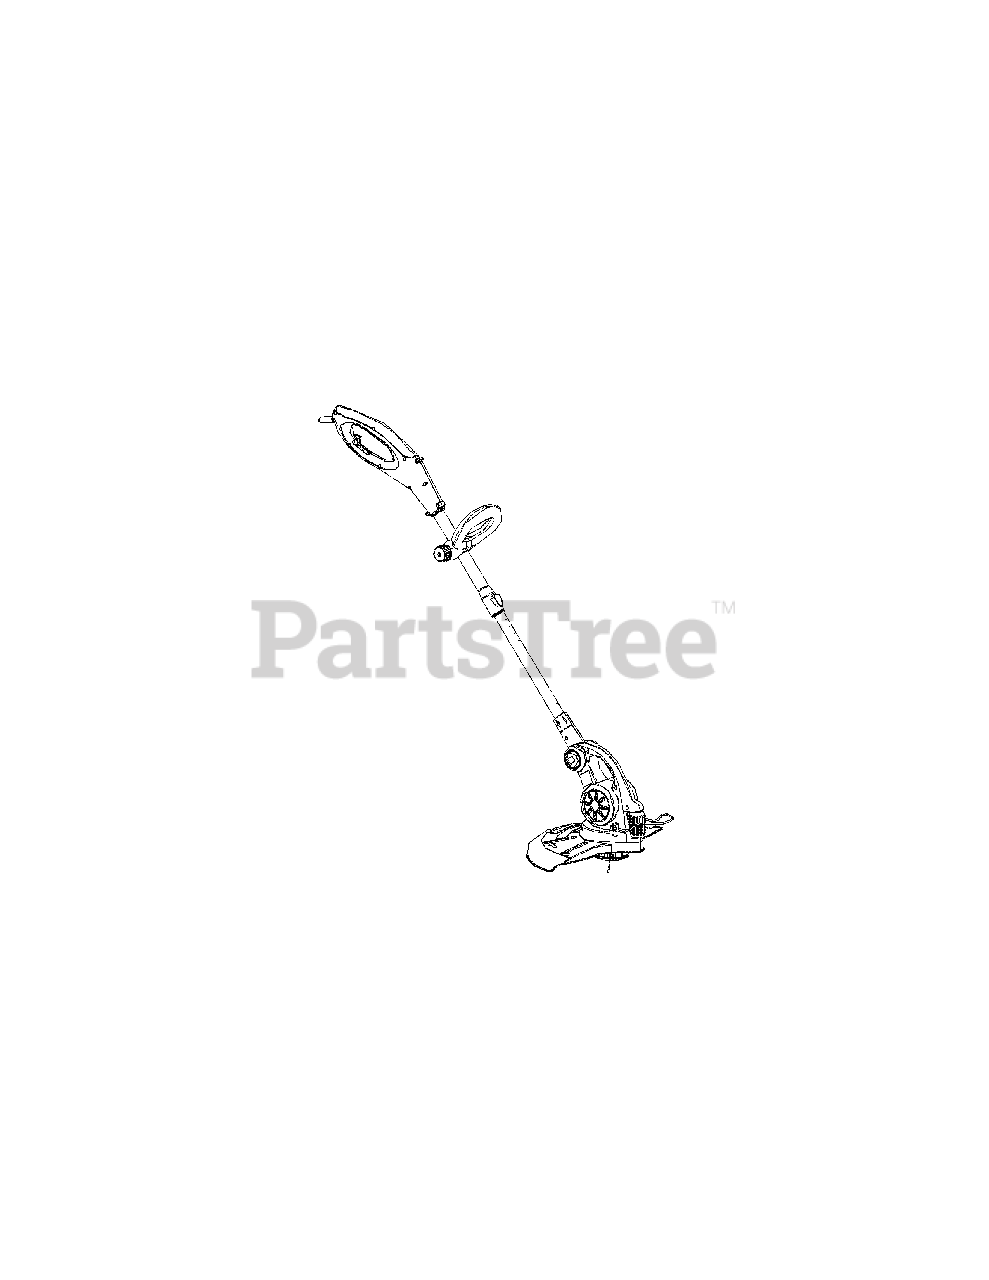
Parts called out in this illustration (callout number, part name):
1	Assist handle assembly
2	Line on spool
4	Wire guard
